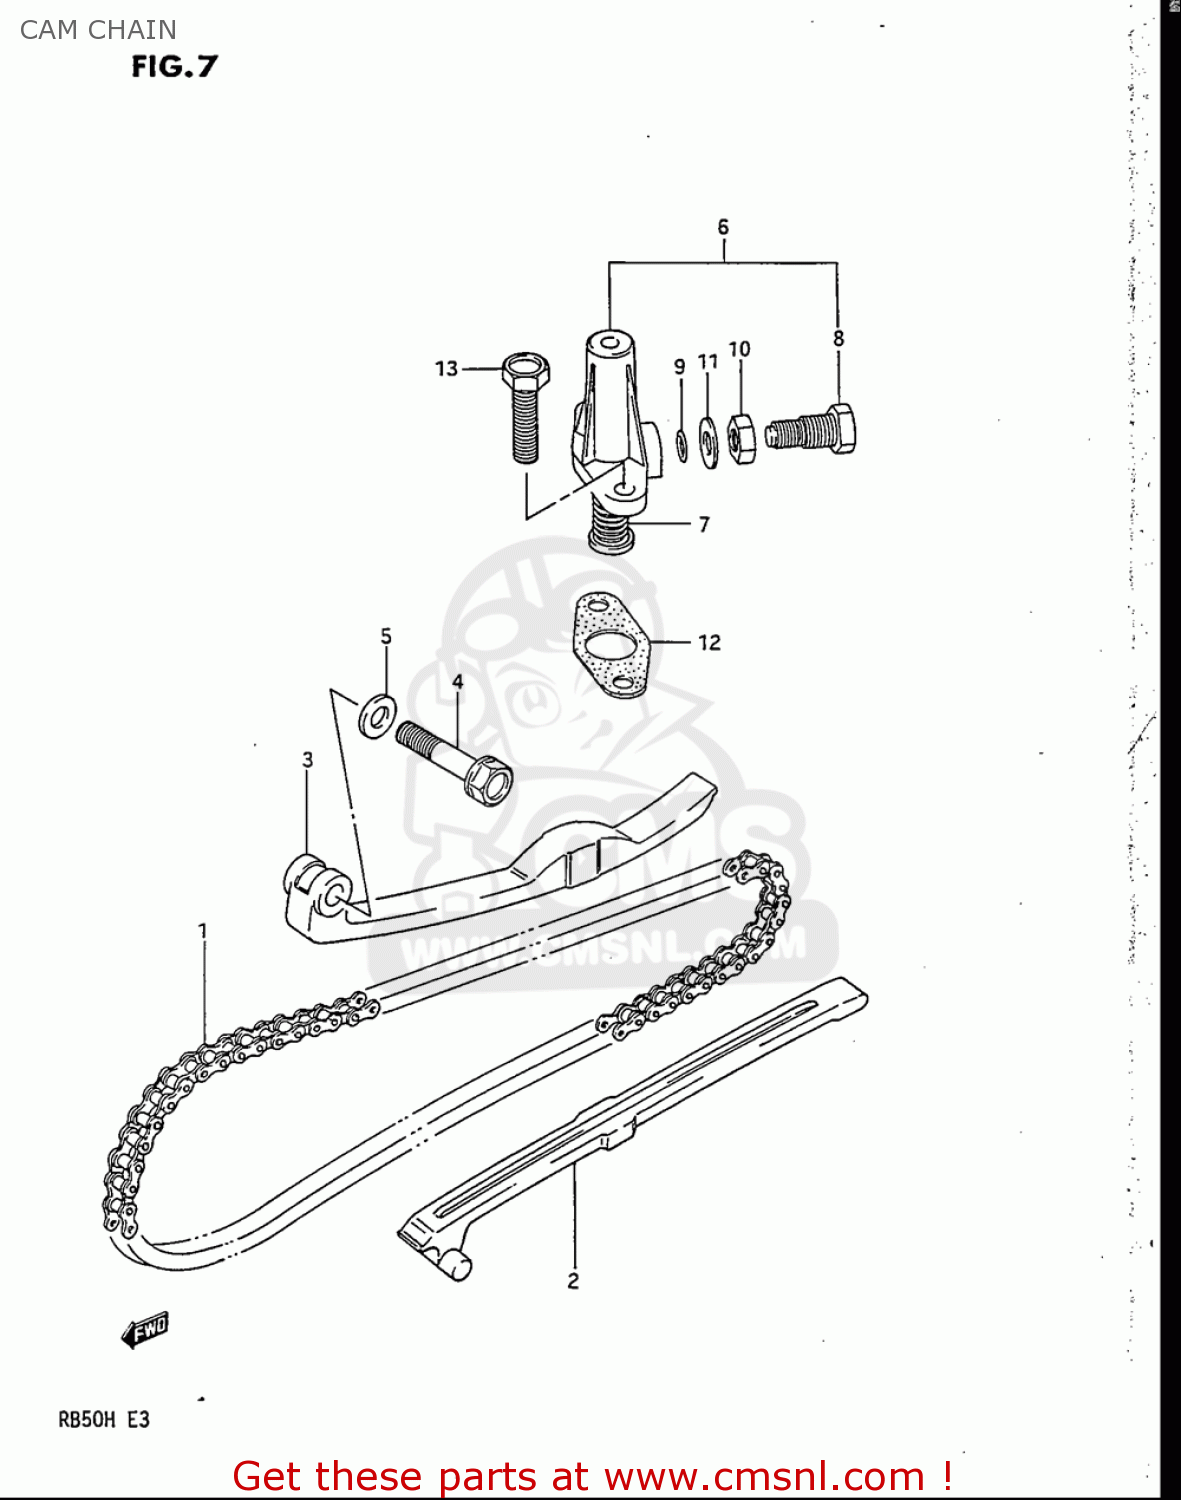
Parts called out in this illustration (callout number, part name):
1	CHAIN,CAMSHAFT DRIVE
4	BOLT(6X30)
5	GASKET(6.2X11X1).2 (NAS)
6	ADJUSTER ASSEMBLY,TENSIONER
9	O RING(D:1.9,ID:5.7)
10	NUT
11	WASHER
12	GASKET,TENSIONER ADJUSTER (NAS)
13	BOLT(6X20)
